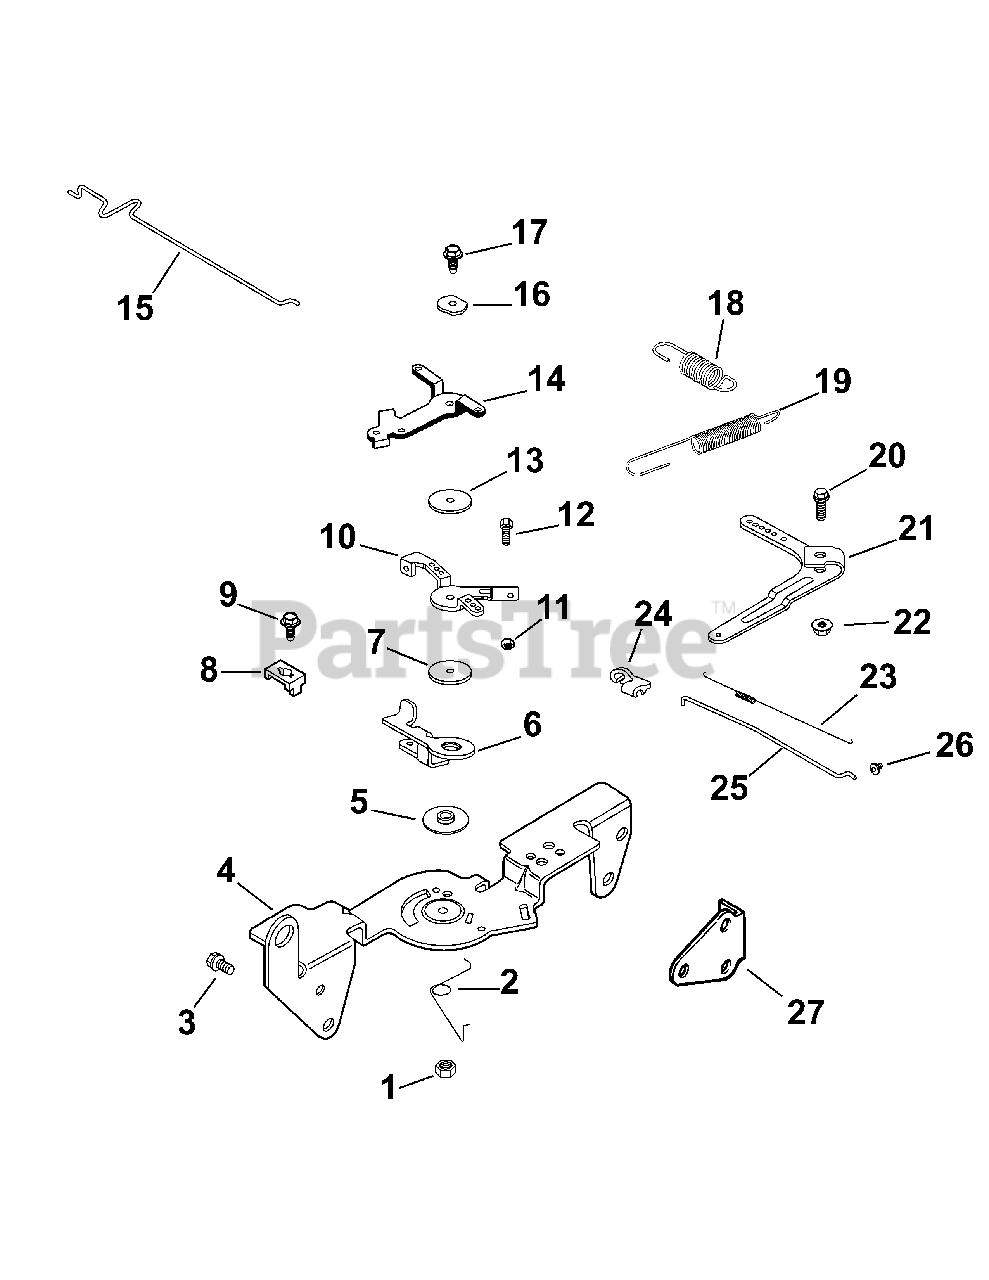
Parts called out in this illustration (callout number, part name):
1	Nut, hex. lock M5x0.8
2	Spring, choke return
3	Screw, hex. flange M6x1.0x16 (4)
4	Bracket, control
6	Lever, throttle actuator
7	Washer, plain
8	Clamp, cable (2)
9	Screw, hex. flange M5x0.8x16 (2)
10	Lever, throttle control
11	Nut, hex M4x0.7
12	Screw, hex. cap M4x0.7x30
13	Washer, plain 5.5 mm
13	Linkage, choke
14	Lever, choke
16	Washer, spring 1/4"
17	Screw, hex. flange M5x0.8x20
18	Spring, governor
19	Spring, governor
20	Screw, hex. flange M6x1.0x25
21	Lever, governor
22	Nut, hex. flange M6x1.0
23	Spring, linkage
24	Bushing, linkage retaining
25	Linkage, throttle
26	Bushing, linkage retaining
27	Bracket, support (2)
